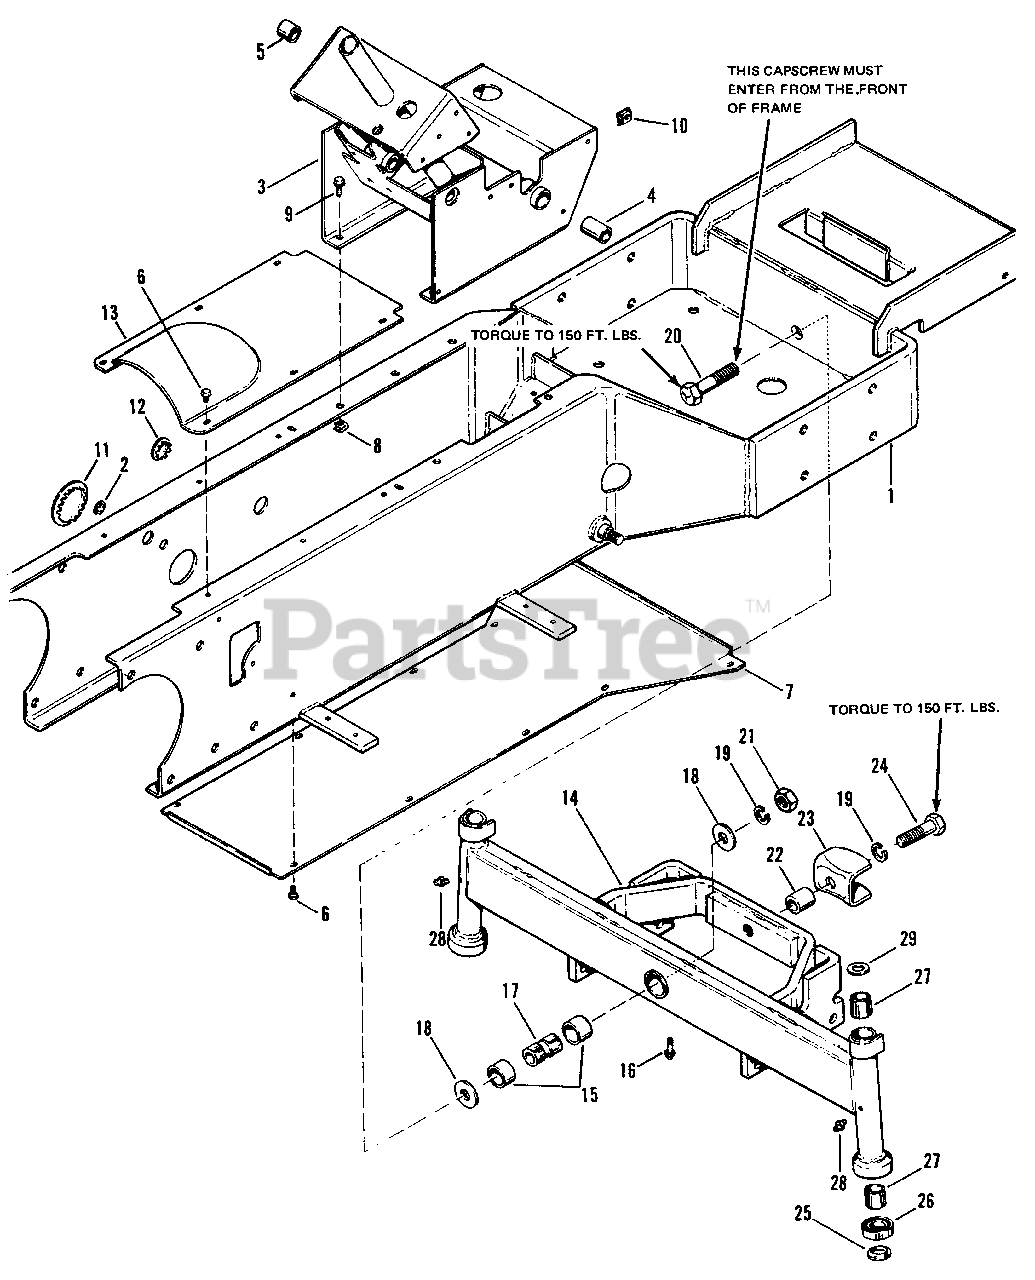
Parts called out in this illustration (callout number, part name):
1	Frame Assembly
2	Hole Plug
3	Support Assembly
5	Sleeve Bearing
6	Washer Hd. Taptite Screw, 1/4"-20 x 3/8" lg.
7	Bottom Cover
9	Washer Hd. Screw
10	Speed Nut
11	Hole Plug
12	Hole Plug
13	Top Cover
14	Axle Assembly
16	Greased Fitting
17	Axle Spacer
18	Thrust Washer
19	Lock Washer, 5/8"
20	Hex Capscrew, 5/8"-11 x 3-1/2"lg.
21	Hex Nut, Full, 5/8"-11
24	Bolt, 5/8"-11 x 2-1/4" lg.
25	Bearing Spacer
26	Thrust Bearing
27	Spindle Bushing
28	Grease Fitting
29	Thrust Washer
